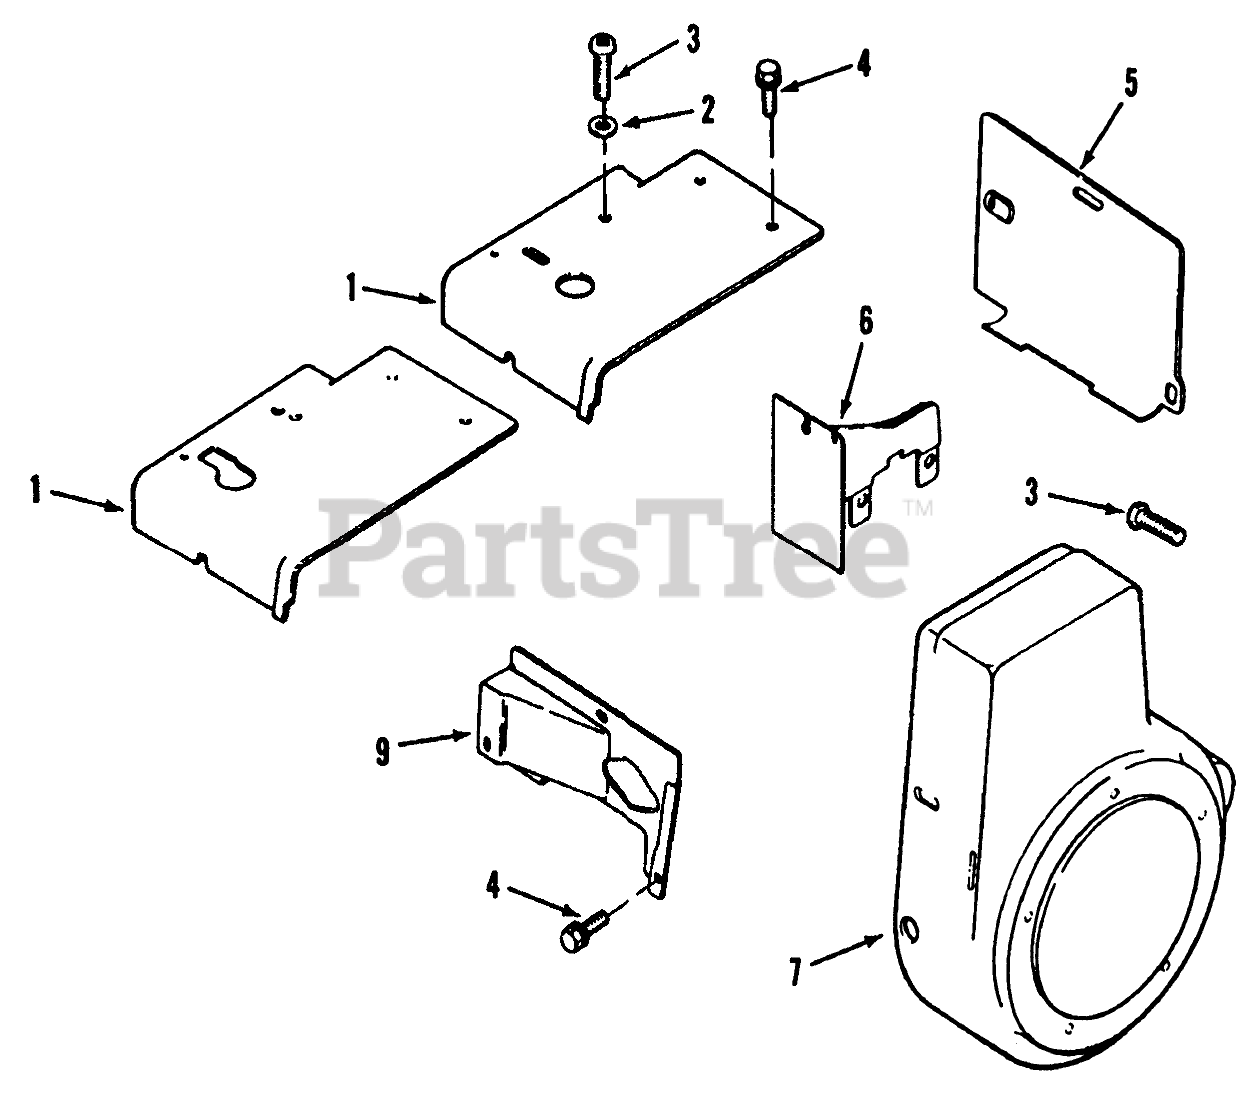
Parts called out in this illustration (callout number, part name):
1	KOHLER 47-063-09
2	KOHLER X-25-53
3	Screw Pozidriv T.H. 1/4-20 x 5/8
4	KOHLER 52-086-11
5	KOHLER 41-063-10
6	KOHLER 47-063-07
7	KOHLER 47-027-42
9	KOHLER 47-063-06
